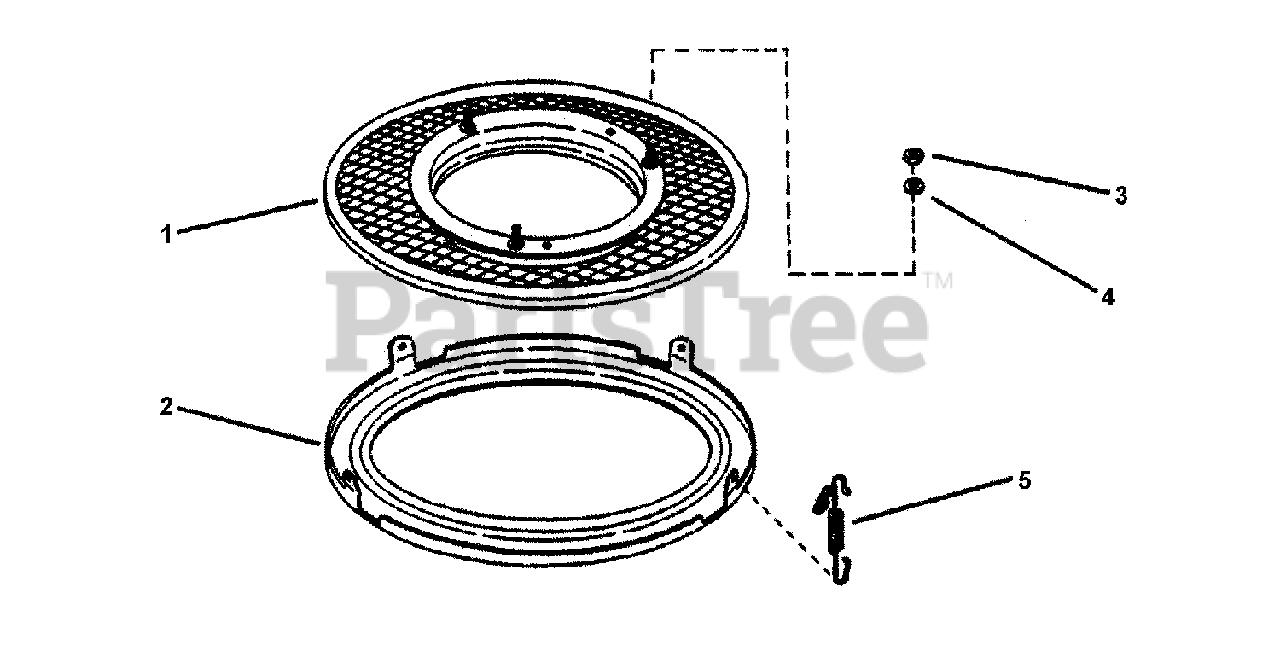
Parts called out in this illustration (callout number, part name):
1	SCREEN, Fastener Assembly
2	RING, Bottom
3	NUT, 5/16-24 Hex, GR5
4	WASHER, 5/16" Split Lock
5	SPRING
